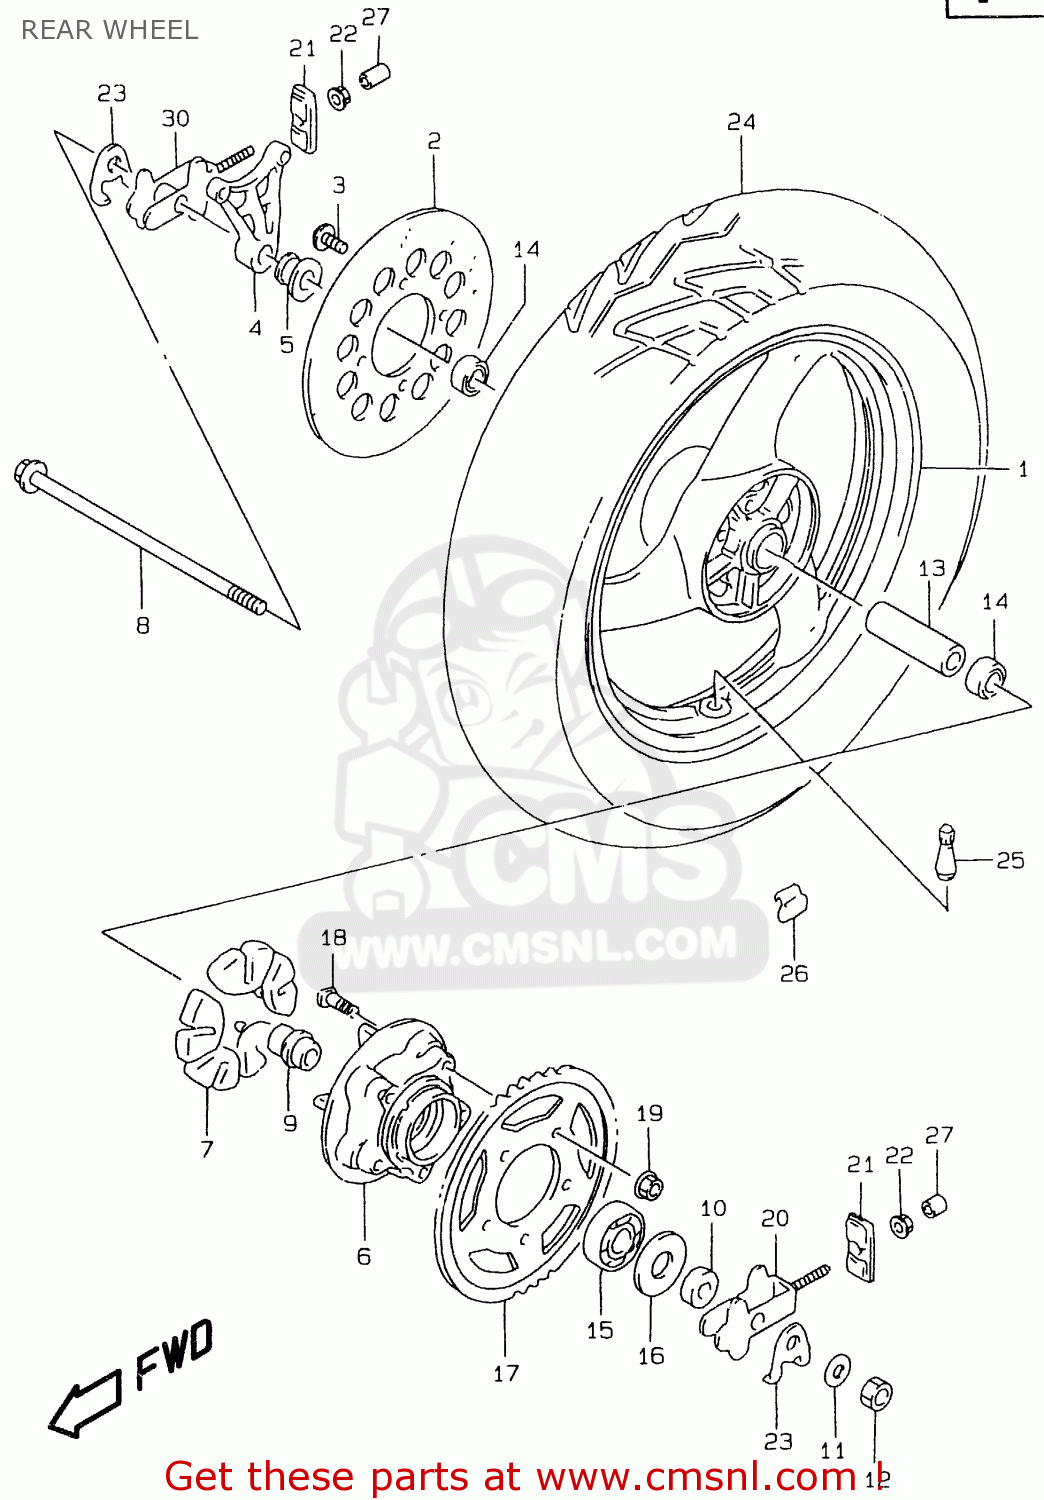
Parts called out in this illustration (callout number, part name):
1	WHEEL,REAR (MT3.50X17)
2	DISC,RR BRAKE
3	BOLT(8X30)
4	BRACKET,RR,CALIPER
5	SPACER,RR AXLE,R
6	DRUM,RR SPROCKET
7	ABSORBER,RR HUB SHOCK
8	AXLE,REAR
9	RETAINER,RR SPROCKET DRUM
10	SPACER,RR AXLE,L
11	WASHER(17X30X3)
12	NUT 16MM
13	SPACER(17.5X25X88)
14	BEARING
15	BEARING(25X62X17)
16	SEAL,OIL(35X62X8)
17	SPROCKET,RR(NT:39-520)
18	BOLT
19	NUT
20	ADJUSTER,CHAIN
21	PLATE,CHAIN ADJUSTER GUIDE
22	NUT
23	WASHER,CHAIN ADJUSTER
24	TIRE,T/L(130/70-17 62H)
25	VALVE ASSY,WHEEL RIM(TR412)
26	BALANCER,WHEEL (10G)
27	CAP,CHAIN ADJUSTER
